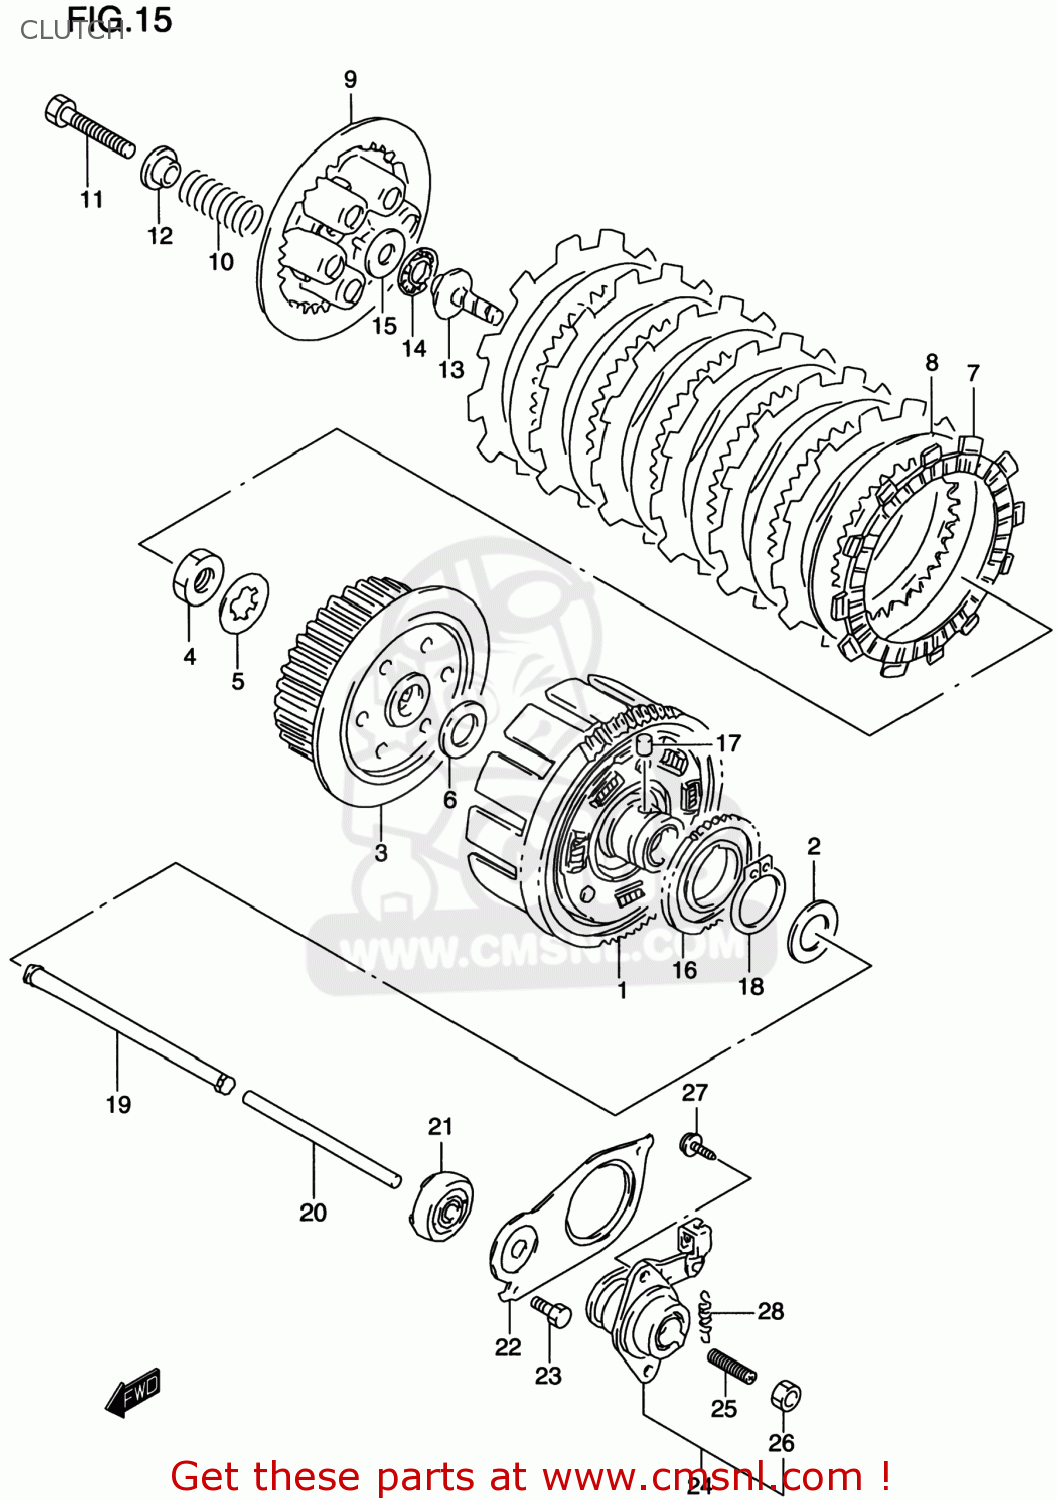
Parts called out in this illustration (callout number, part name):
1	GEAR ASSY,PRI DRIVEN
2	WASHER
3	HUB,CLUTCH SLEEVE
4	NUT
5	WASHER,LOCK
6	WASHER(20X44X3)
7	PLATE,CLUTCH DRIVE (NAS)
8	PLATE,CLUTCH DRIVEN T: (NAS)
9	DISC,CLUTCH PRESSURE
10	SPRING
11	BOLT(6X40)
12	SPACER,CLUTCH SLEEVE HUB
13	PIECE,CLUTCH PUSH
14	BEARING(15X28X2)
15	WASHER(15.5X28X1)
16	GEAR,OIL PUMP DRIVE(NT:39)
17	PIN(6X6)
18	CIRCLIP
19	ROD,PUSH,R
20	ROD,CLUTCH PUSH,L
21	SEAL,OIL(6X34X10)
22	RETAINER,PUSH ROD OIL SEAL
23	BOLT
24	SCREW ASSY,CLUTCH RELEASE
25	SCREW(6X25)
26	NUT
27	SCREW 6X16
28	SPRING
